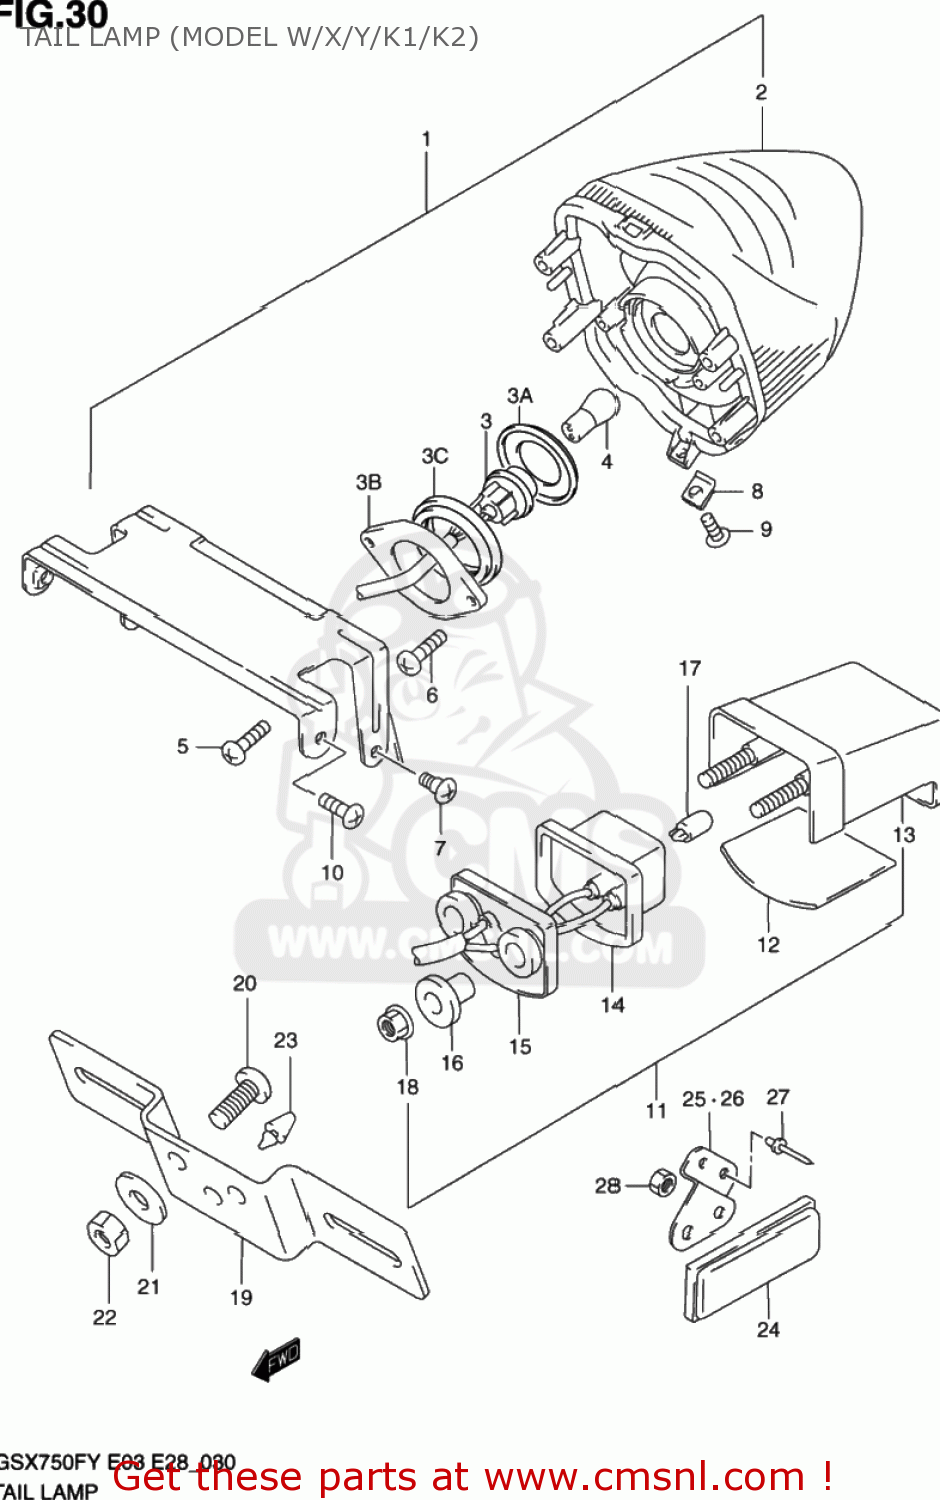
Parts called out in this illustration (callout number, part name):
1	LAMP ASSY,RR COMBINATION
2	LAMP UNIT
3	SOCKET & CORD
3A	PLATE NO.1
3B	PLATE NO.2
3C	CUSHION
4	BULB(12V21/5W)
5	SCREW
6	SCREW
7	SCREW(5X12.8)
8	NUT
9	SCREW
10	SCREW
11	LAMP ASSY,LICENSE PLATE
12	LENS
13	COVER
14	HOUSING
15	SOCKET & CORD
16	SPACER
17	BULB(12V5W)
18	NUT
19	BRACKET,LICENSE PLATE
20	SCREW
21	WASHER(6.5X20X1.6)
22	NUT 6MM
23	CUSHION
24	REFLECTOR ASSEMBLY,REAR
25	BRACKET,RR SIDE REFLECTOR,R
26	BRACKET,RR SIDE REFLECTOR,L
27	RIVET
28	NUT
